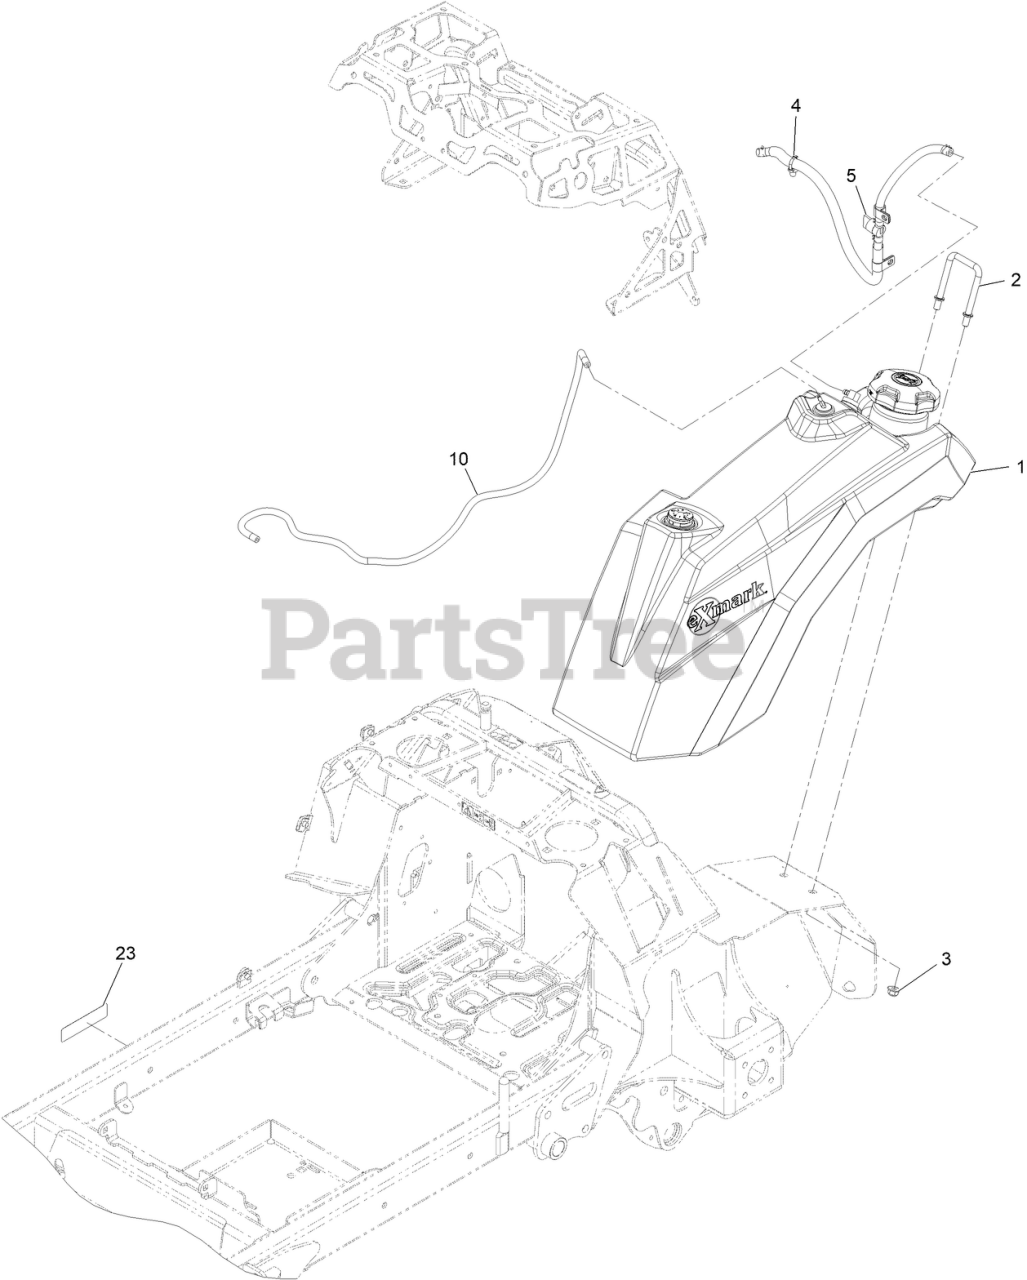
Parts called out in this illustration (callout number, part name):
1	ASM-FUEL TANK
2	CLAMP, TANK
3	NUT-HF, NI
4	CLIP-TIE
5	ASM-FUEL LINE & VALVE
10	HOSE-FUEL
23	DECAL-ARRESTOR, SPARK
